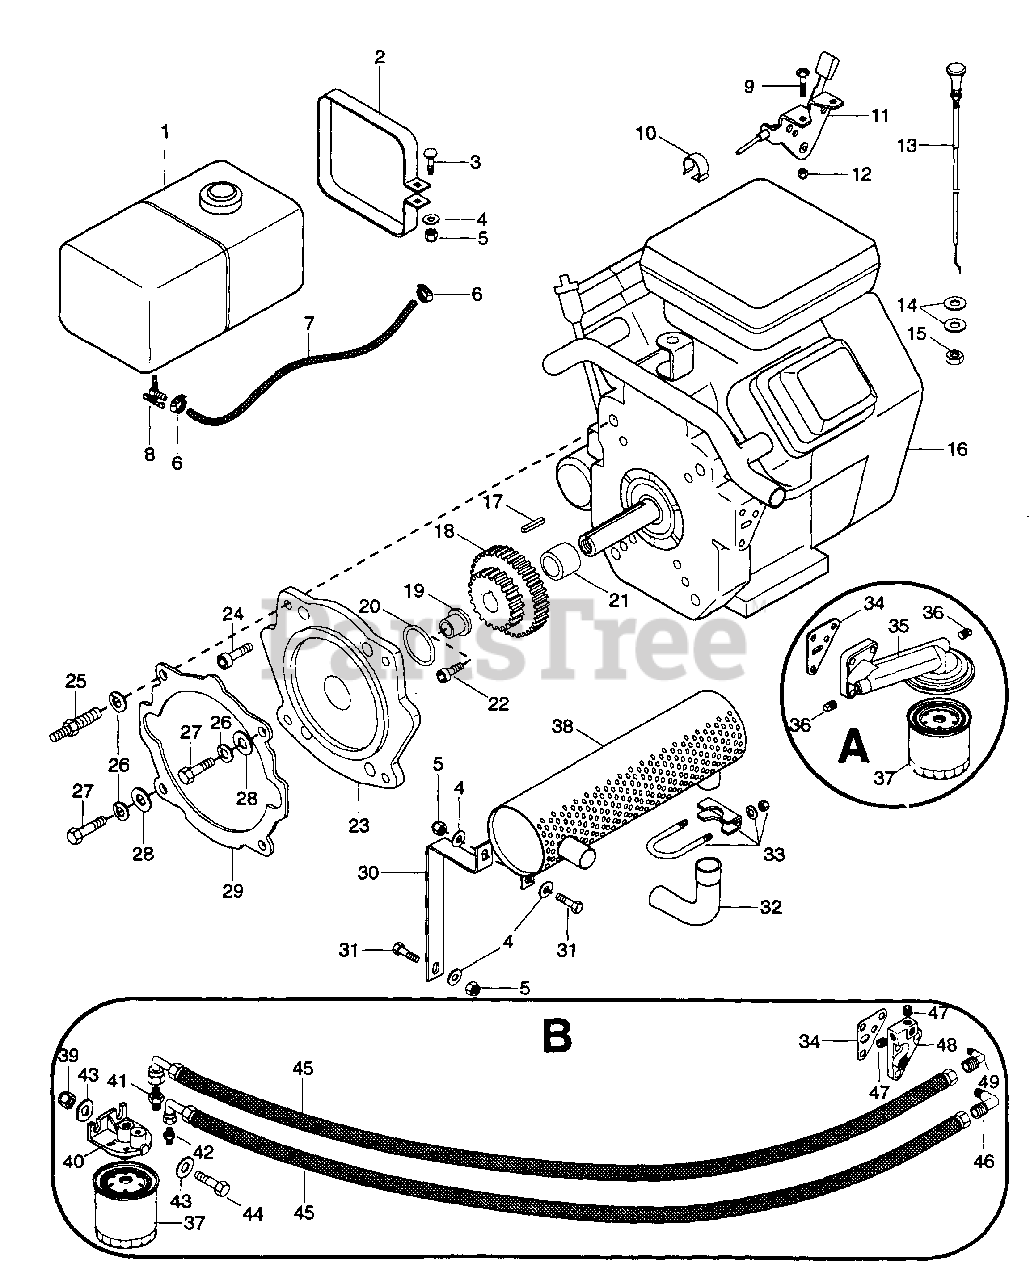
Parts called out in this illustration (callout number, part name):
1	TANK, FUEL, W/CAP, BLACK, 2-WHL TR
2	STRAP, FUEL TANK
3	BLT-RDHDSQNK .25-20 X 1.75 SHT PL
4	WSHR-FL-STL .312 X .734 X .065 PL
5	NUT-LK-NYL .250-20 PL
6	HOSE CLAMP
7	GAS LINE-BULK
8	VLV, AND STRAINER
9	SCR-MCH 10-24 X .50 PHD
10	CLAMP
11	CONTROL, CHOKE
12	NUT-LK 10-24 NY PL
13	LVR, CHOKE CONTROL 8 HP
14	WSHR-FL-STL .406 X .812 X .065 PL
15	NUT JAM .375-24 PL
16	ENG, 16-HP B & S(2-WHL)
17	KEY-SQ .248 X 1.0 X .248
18	GR, B & S ENGINE
19	PILOT, GEAR
20	O-RING 1.850 X 2.27 X .210
21	BUSH., S 1.05 X 1.31 X 1.54 ST
22	SCR-MCH .38-24 X 1.00
23	ADAPTER, B & S ENGINE
24	SCR-SKH .44-14 X 1.00
25	STUD
26	WSHR-LOCK .438 X .133 HVY
27	BLT-HEX .44-14 X 1.50
28	WSHR-FL-STL .469 X .938 X .065
29	GSKT, CHASSIS TO ADAPTER
30	BRKT, EXHAUST
31	BLT-HEX .25-20 X 1.00 PL GR 5
32	ELBOW
33	CLAMP-MUFFLER 1.25
34	GASKET, OIL FILTER ADAPTER
35	OIL FILTER MANIFOLD S/N 201 AND UP.
36	PLUG-PIPE 1/16-27 S/N 201 AND UP.
37	FILTER, OIL
38	MUFFLER, 16 HP
39	NUT-LK-NYL .312-18 PL S/N 101-200
40	ASM, OIL FILTER MOUNT S/N 101-200
41	FITTING, STR 6 FT X-S S/N 101-200
42	FITTING, STR 6-2 FT X-S S/N 101-200
43	WSHR-FL-STL .344 X .688 X .065 S/N 101-200
44	BLT-HEX .31-18 X 1.25 PL GR 5 S/N 101-200
45	ASM, HOSE S/N 101-200
46	ADPTR-PIPE .56-18 S/N 101-200
47	PLUG, 1/8-27 PIPE HEX SCKT S/N 101-200
48	ADPT, OIL FILTER S/N 101-200
49	ADPTR-PIPE .90 X 1.06 S/N 101-200
